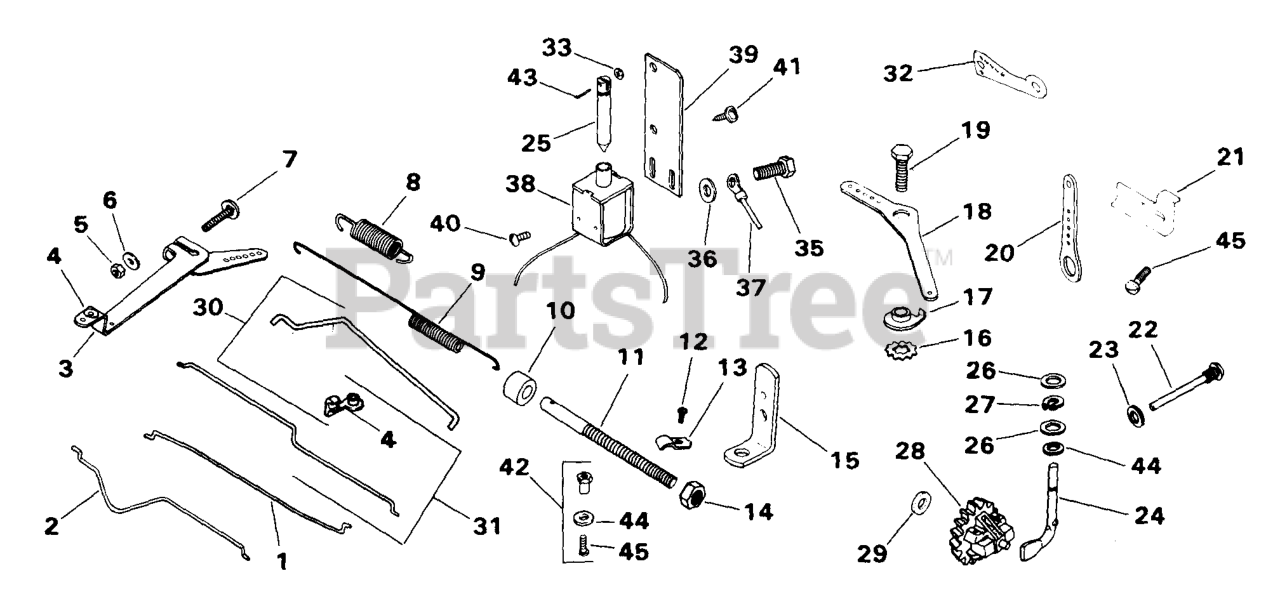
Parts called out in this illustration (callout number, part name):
3	ARM, GOVERNOR - DISCONTINUED
4	BUSHING - USE 25 158 11
5	NUT, 1/4-20 GRADE 2 USE 25 100 20-S
6	WASHER, FLAT 1/4"
7	BOLT, RD HD SQ NCK 1/4-20X1"
8	SPRING - (#DSC)
12	SCREW, WSH HD TAP #10-24X13/32" USE 25 086 109-S
21	STOP, HIGH SPEED - DISCONTINUED
24	SHAFT - (#DSC)
26	WASHER, FLAT 1/4" (O.D. 1/2")
28	KIT, GOVERNOR GEAR
31	KIT, GOVERNOR LINKAGE-DISCONTINUED
44	WASHER, FLAT 1/4"
45	SCREW, WSH HD TAP 1/4-20X3/4" USE 25 086 100-S
